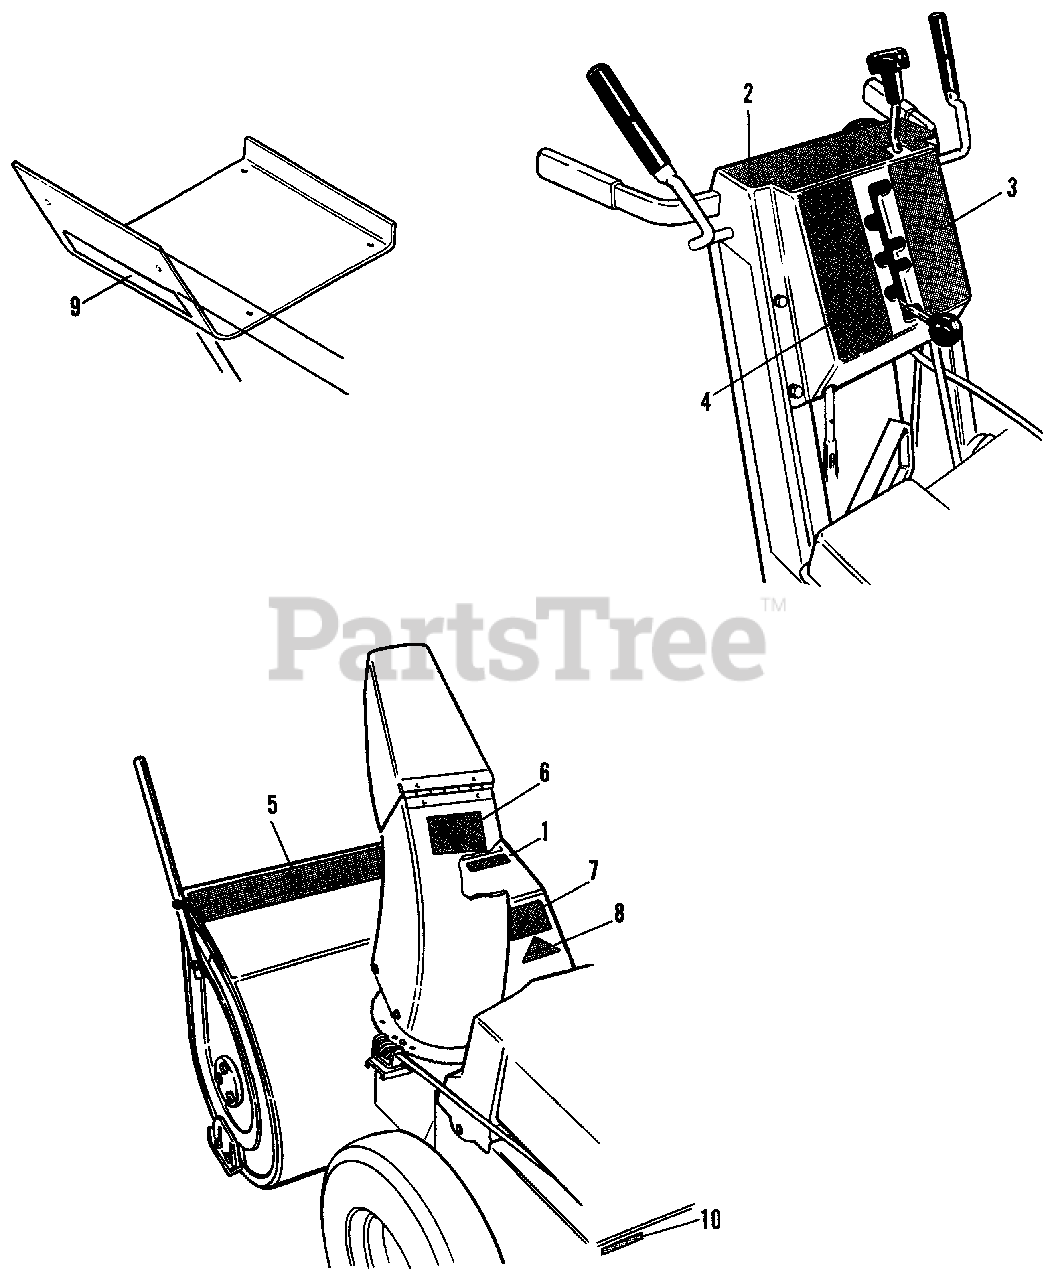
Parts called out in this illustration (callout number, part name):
1	DECAL, Housing, LARGE FRAME SNOWTHROWERS with Power Boost, 860S (1691778)
1	DECAL, Housing, LARGE FRAME SNOWTHROWERS with Power Boost, 860SE (1691777)
2	DECAL, Dash (1691777, 1691778)
2	DECAL, Dash (1691900, 1691946)
3	DECAL, Shift Pattern, L.H.
4	DECAL, Shift Pattern, R.H.
5	DECAL, Auger, Simplicity Logo
5	DECAL, Auger, LARGE FRAME SNOWTHROWERS with Power Boost, Sno-Away 860
6	DECAL, Danger, Blower
7	DECAL, Danger, Auger
8	DECAL, OPEI
9	DECAL, Touch Up Paint
10	I.D. PLATE
